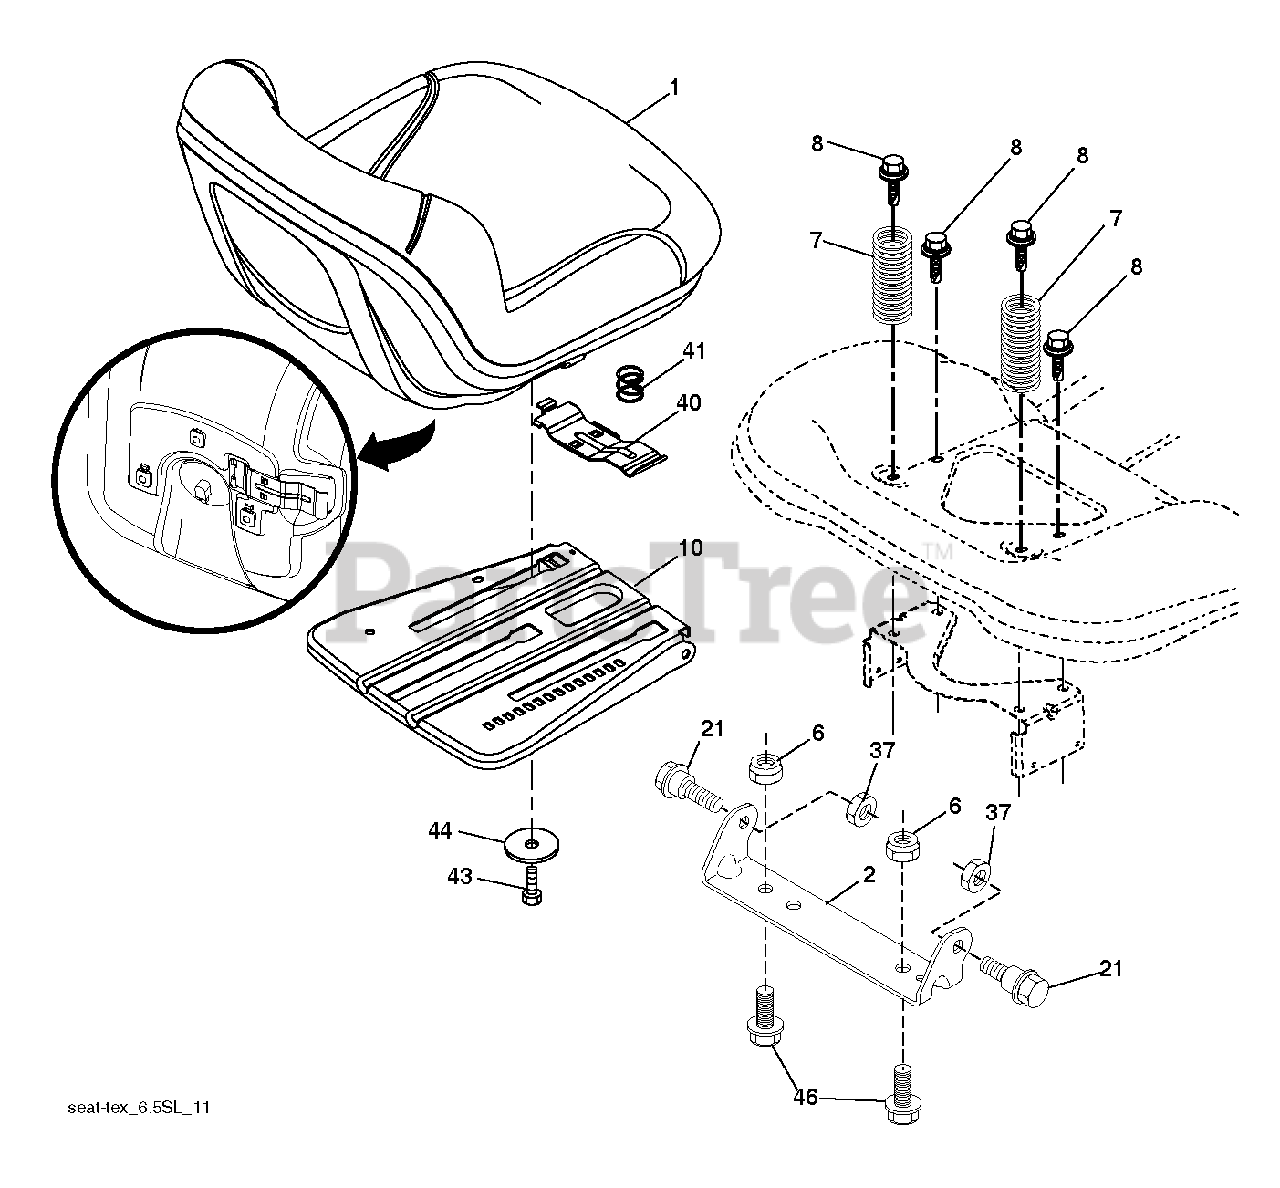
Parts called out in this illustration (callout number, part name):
1	SEAT.TG150.BLK.NLOGO.
2	BRKT.PIVOT.FENDER
6	NUT
7	Compression Spring, Seat Black
8	BOLT, 5/16-18 X 1 3/4
10	PAN.ASM.SEAT.3PT
21	Shoulder Bolt, 5/16-18 X 5/8
37	NUT.71038.31-18.HEX.NYLOCK
40	HANDLE.SLIDE.SEAT.TEX.BLACK
41	SPRING.LATCH.SEAT.TEX
44	WASHER 13/32 X 2-3/8 X 12GA
46	BOLT.3/8-16X1;1.25OD.WSHR.SEMS
